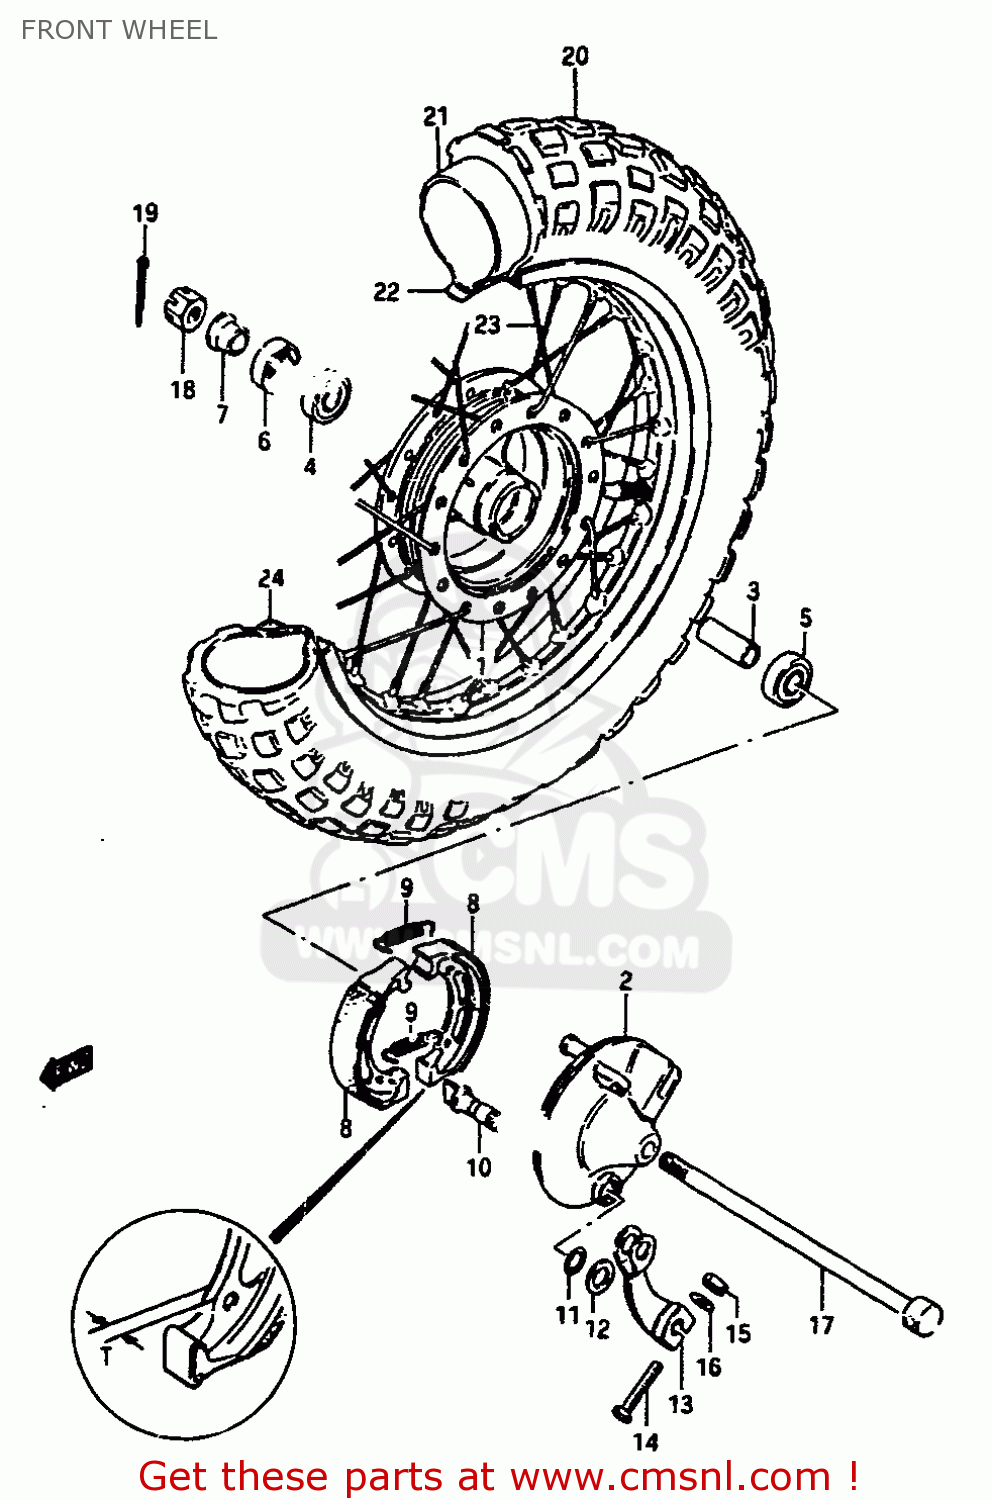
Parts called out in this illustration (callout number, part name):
1	HUB,FR WHEEL
2	PANEL,FR BRAKE ANCHOR
3	SPACER(10.2X16X47)
4	BALL BEARING K
5	BEARING
6	SEAL,OIL(15X27X6)
7	SPACER,AXLE
8	SHOE,BRAKE
9	SPRING(L:34)
10	CAM,FRONT BRAKE
11	O RING(D:2.4,ID:9.8)
12	WASHER (10.5X18X1)
13	LEVER,FR BRAKE CAM
14	BOLT
15	NUT
16	WASHER
17	AXLE,RR
18	NUT
19	PIN 20X20
20	TIRE
21	TUBE,INNER
22	PROTECTOR,INNER TUBE
23	SPOKE SET,RR
24	RIM,WHEEL
